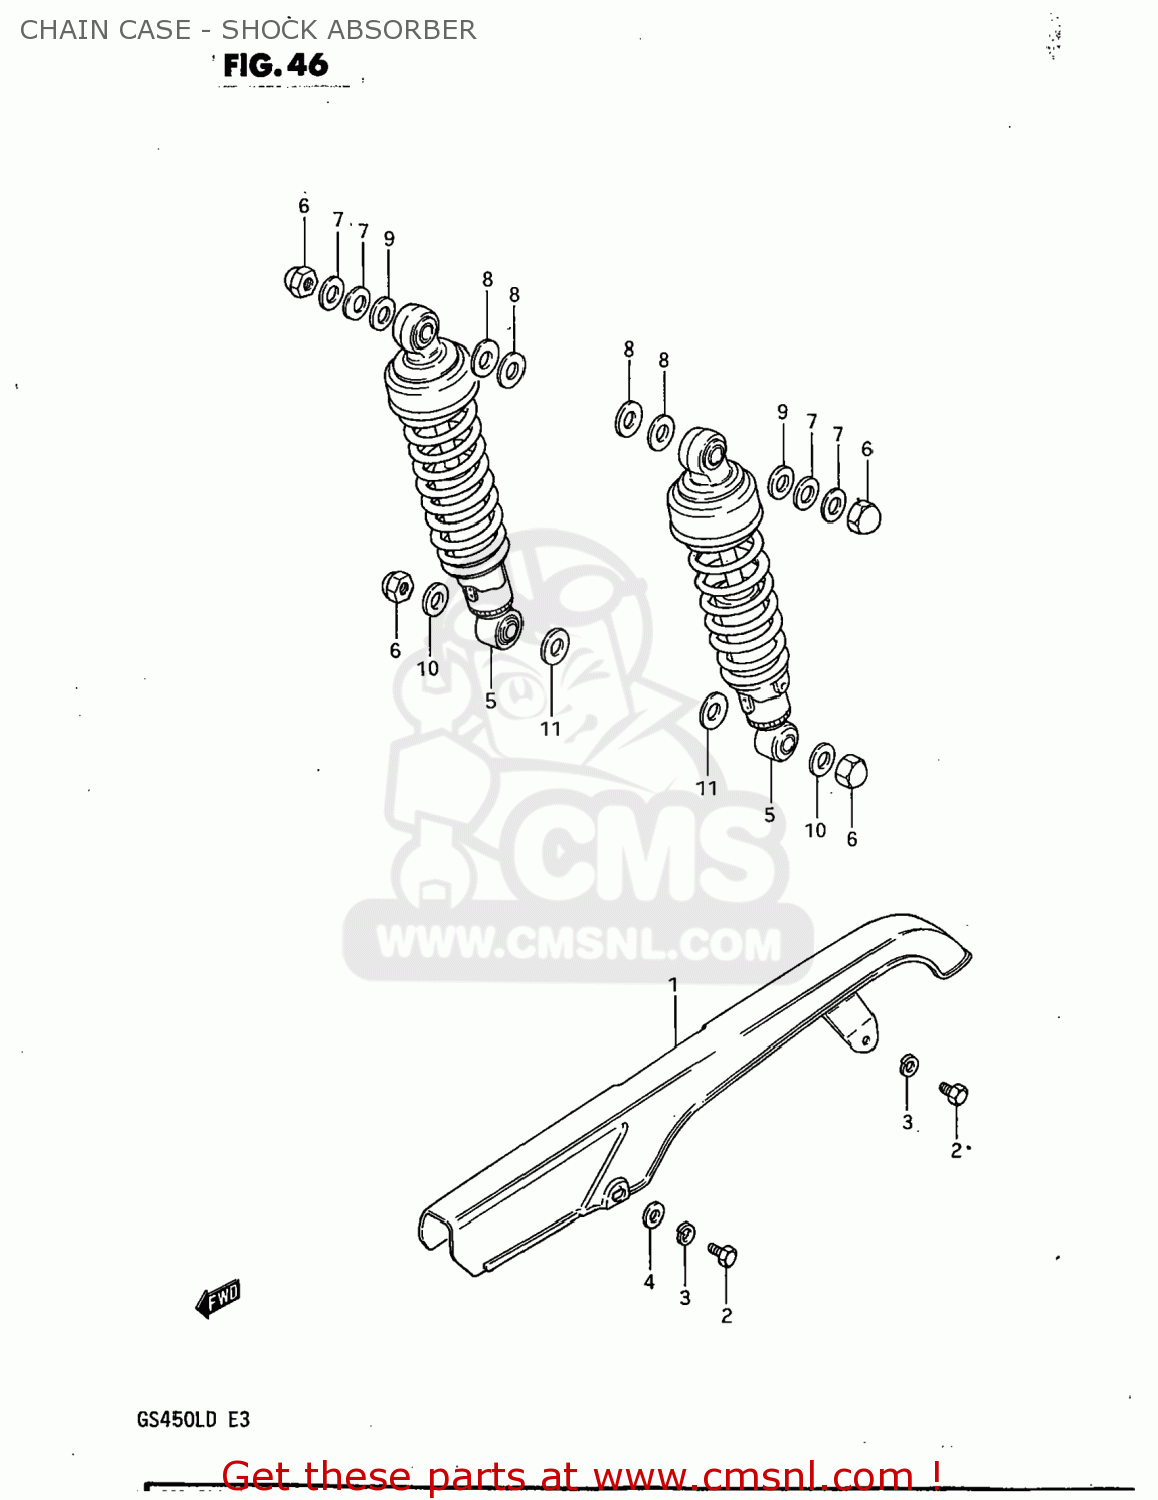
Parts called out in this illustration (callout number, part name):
1	CASE,CHAIN
2	BOLT
3	LOCK WASHER
4	WASHER
5	ABSORBER ASSY,RR SHOCK
6	NUT, LOWER LH
7	WASHER(10.5X24X3.2)
8	WASHER
9	WASHER (12.5X24X3.2)
10	WASHER
11	WASHER (12.5X24X1.6)
